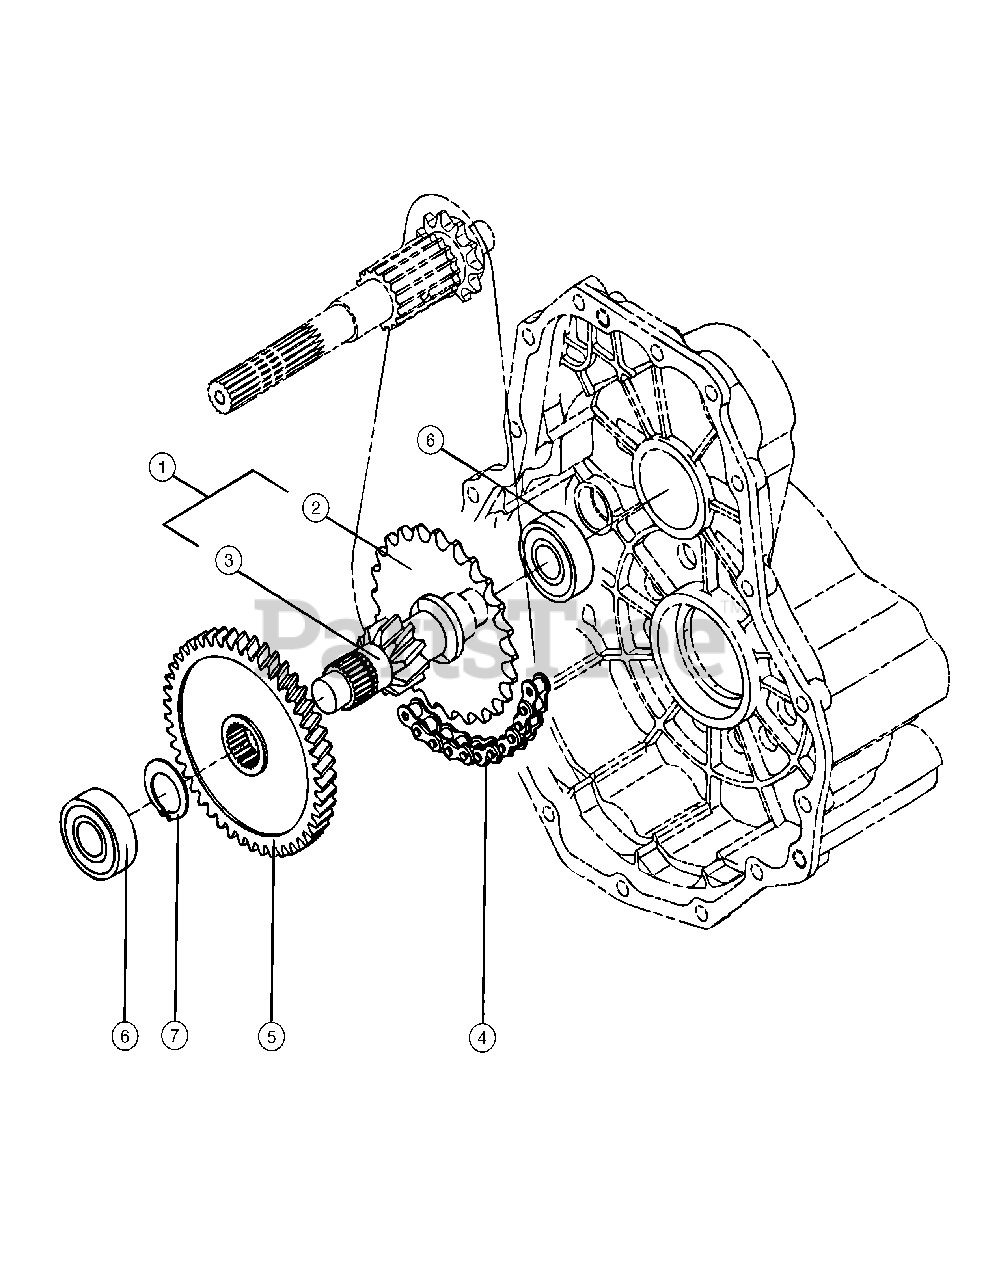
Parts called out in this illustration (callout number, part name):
1	Reduction Shaft Assembly
2	Sprocket, 27
3	Shaft, Reduction
4	Chain, 40 x 34
5	Gear, 46H, Reduction
6	Bearing, 6204R, SH2
7	Ring, 26
